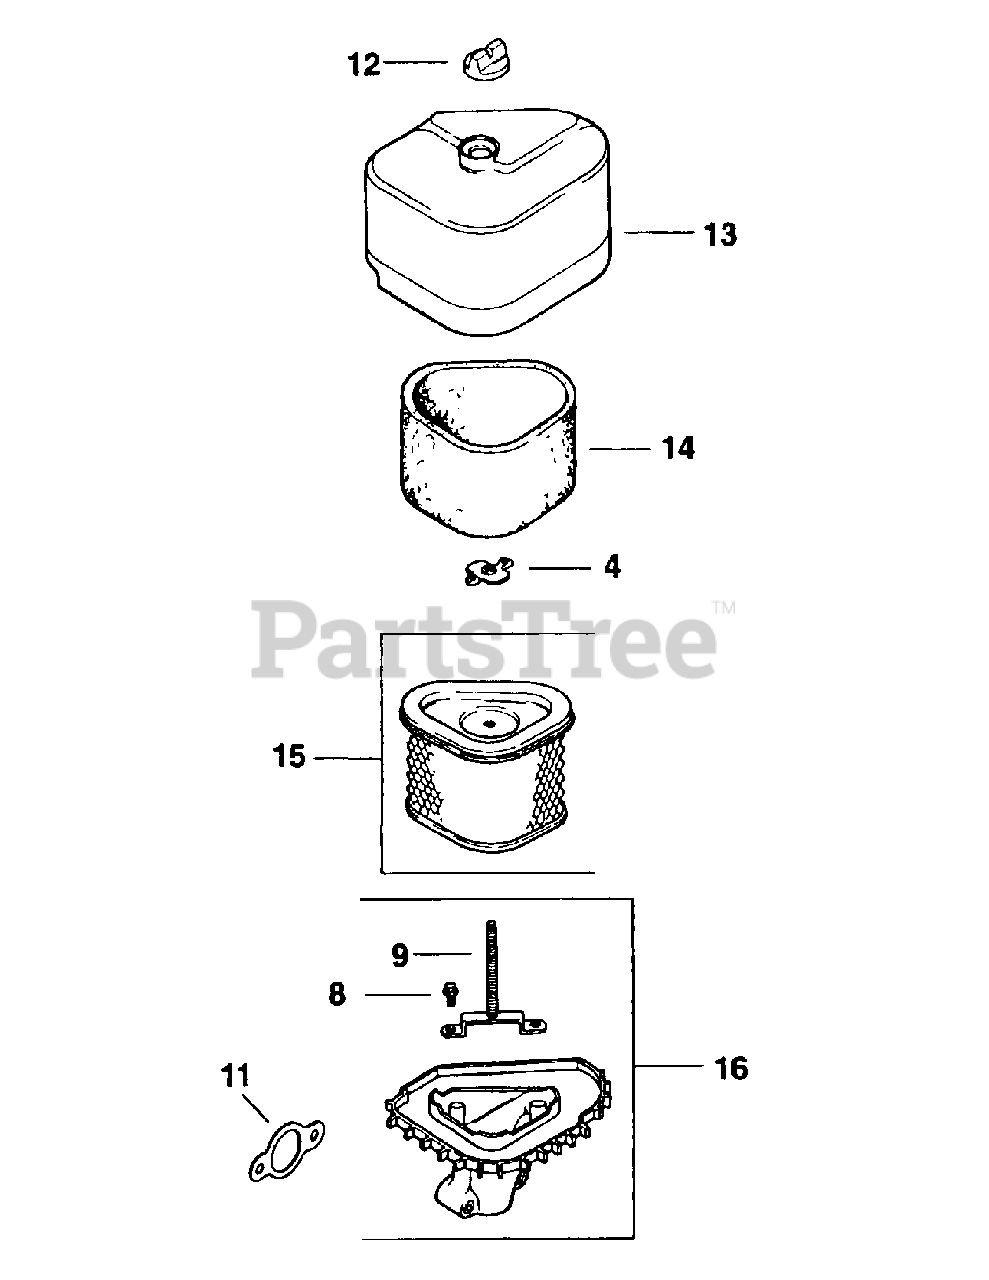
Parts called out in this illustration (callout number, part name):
4	Nut, Wing
8	Screw, Hex Cap #10 Hi-Lo
9	Stud, Mounting Plate
11	Gasket, Air Cleaner
12	Knob, Air Cleaner Cover
13	Cover, Air Cleaner
14	Precleaner
15	Elements, Air Cleaner & Precleaner
16	Base, Air Cleaner
